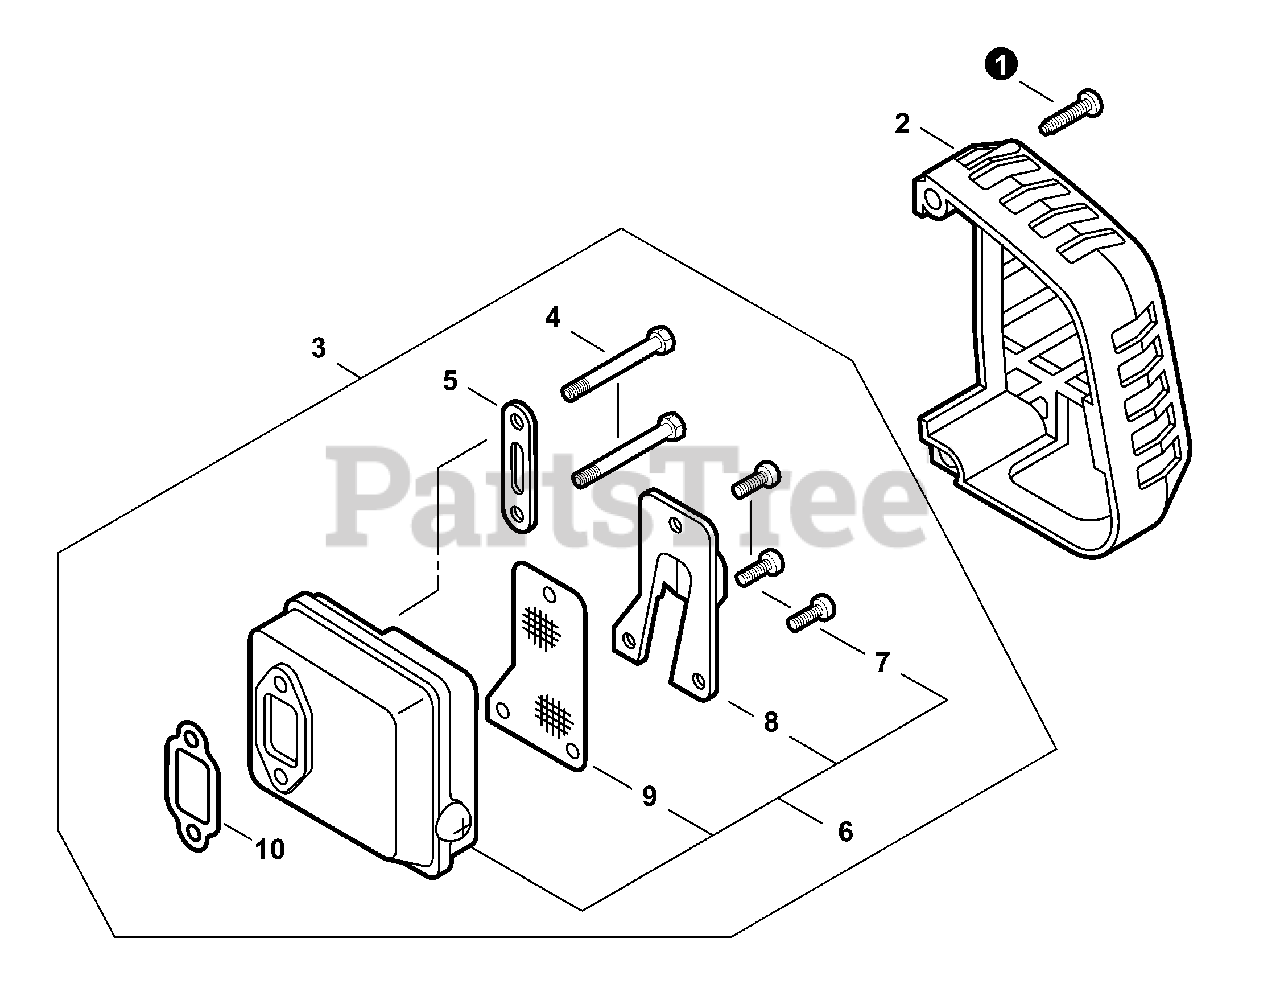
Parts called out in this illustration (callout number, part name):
1	SCREW 5×20
2	COVER, MUFFLER
3	MUFFLER ASSY
4	BOLT, FLANGE HSH 5×45
5	PLATE, EYE
6	MUFFLER
7	SCREW 4
8	COVER, MUFFLER
9	SCREEN, SPARK ARRESTER
10	GASKET, MUFFLER
